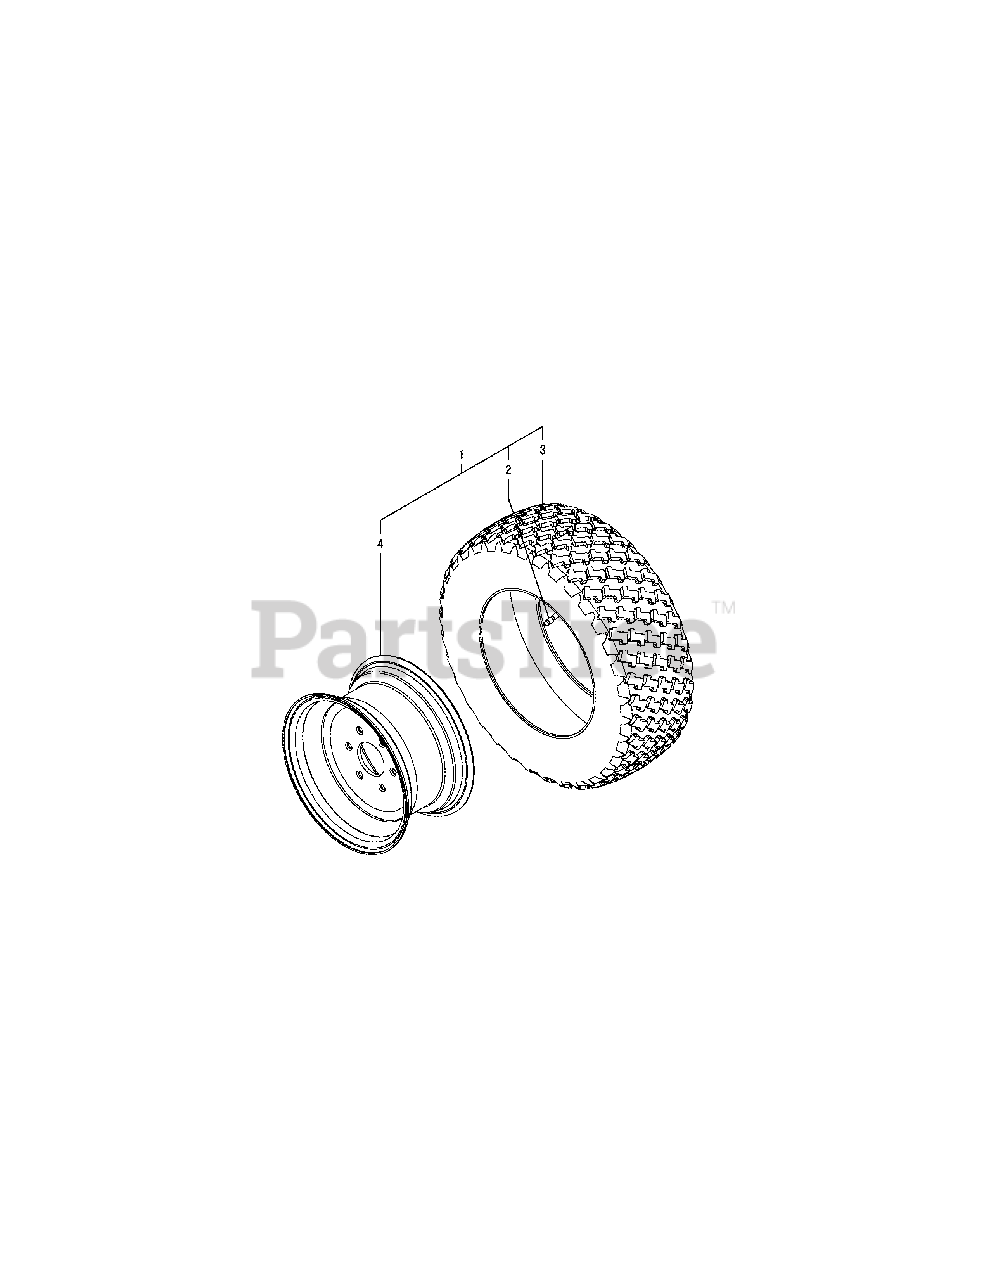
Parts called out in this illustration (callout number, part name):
1	R3 TIRE ASM, FRONT
2	VALVE, FRONT TIRE
3	R3 TIRE 27X10.5-15, TURF
